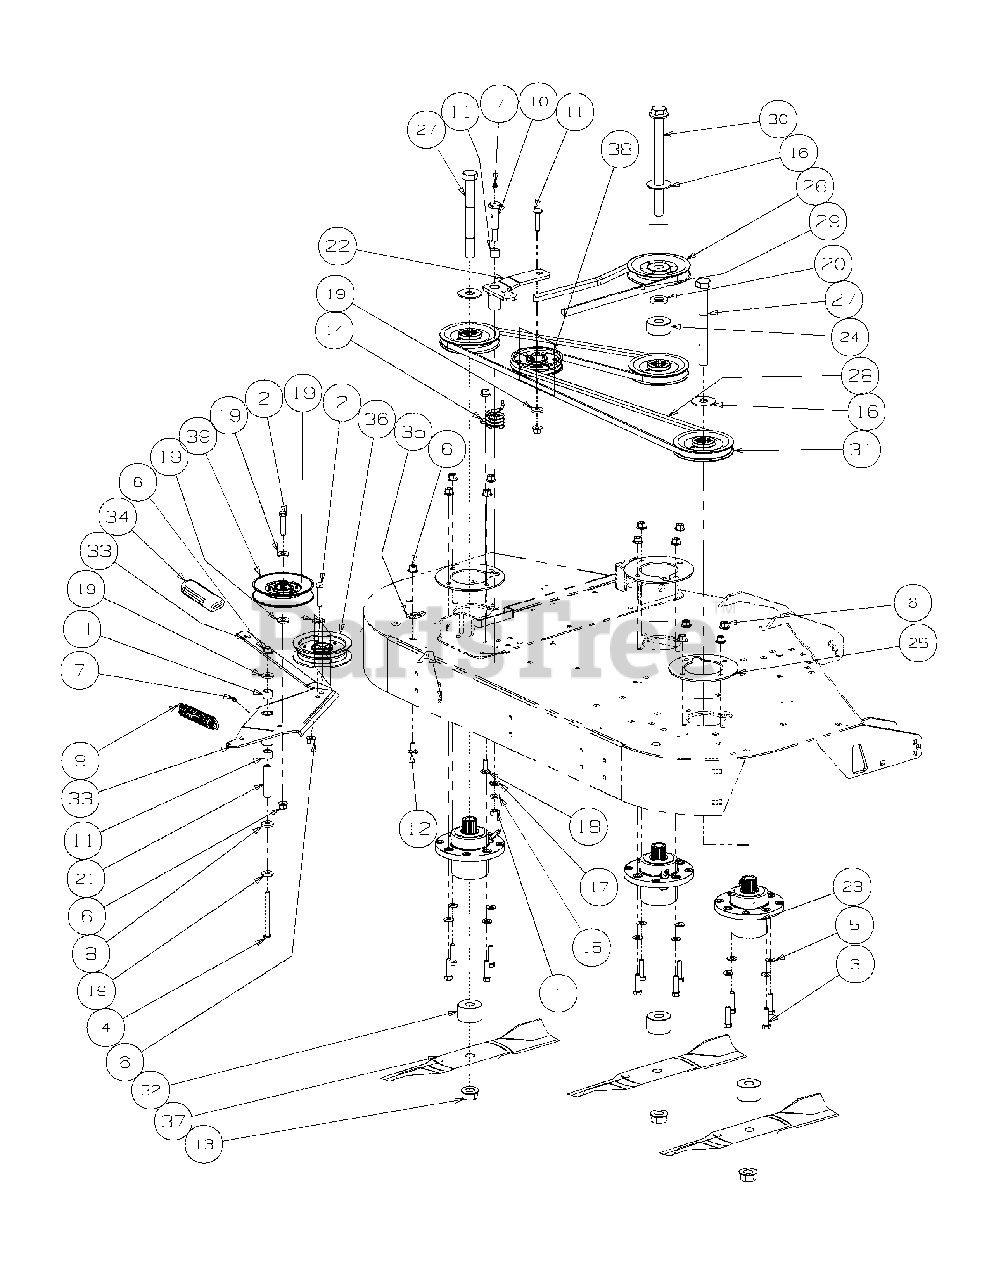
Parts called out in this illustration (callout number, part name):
1	Hex Nut, 7/16-14
2	Hex Cap Screw, 3/8-16 x 1-3/4
3	Hex Cap Screw, 3/8-16 x 1-1/2
4	Hex Cap Screw, 3/8-16, 4.00
5	Flat Washer, 3/8
6	Flange Lock Hex Nut, 3/8-16
7	Grease Fitting, 1/4-28 x 3/16
8	Idler Washer
9	Spring Extension, .94 OD X 7.57, Silver
10	Shoulder Screw, 7/16-14
11	Hex Carriage Screw, 3/8-16, 1.75
12	Carriage Bolt, 3/8-16 x .75 Lg.
13	Flange Hex Nut, 3/4-16
14	Torsion Idler Spring
15	Lock Washer, 7/16
16	Flat Washer, .781 ID 2.00 OD, .105
17	Flat Washer, .469 ID, .875 OD, .105
18	Carriage Bolt, 3/8-16 x 1
19	Flat Washer, .406 ID, 1.0 OD, .105
20	Spacer .812 ID x .268 LG
21	Spacer, .39 ID x .625 OD x 2.75
22	Idler Arm Assembly includes:
22	Bearing
23	Aluminum Spindle Assembly
24	Spacer, .760 ID x 2.000 OD x 1.1
25	Spindle, Aluminum Cast Support Plate
26	V-Pulley 5.25 OD
27	Hex Cap Screw, 3/4-16, 7.00
28	V-Belt, A Section x 105.3
29	V-Belt, B Section x 87.2
30	Hex Cap Screw, 3/4-16, 9.00
31	V-Pulley, 5.00 OD
32	Spacer .760 ID x 2.00 OD x 1.28
33	Idler Arm Assembly Service Kit
33	Bearing for Idler Arm
34	Idler Tension Handle Grip
35	Tension Spring Bracket
36	PULLEY-FLAT IDLER 4.875
37	Blade, 17.0, Hi-Lift, 0.756 ID
38	Idler Pulley, 4.06 Dia.
39	Idler Pulley, 5.06 Dia.
